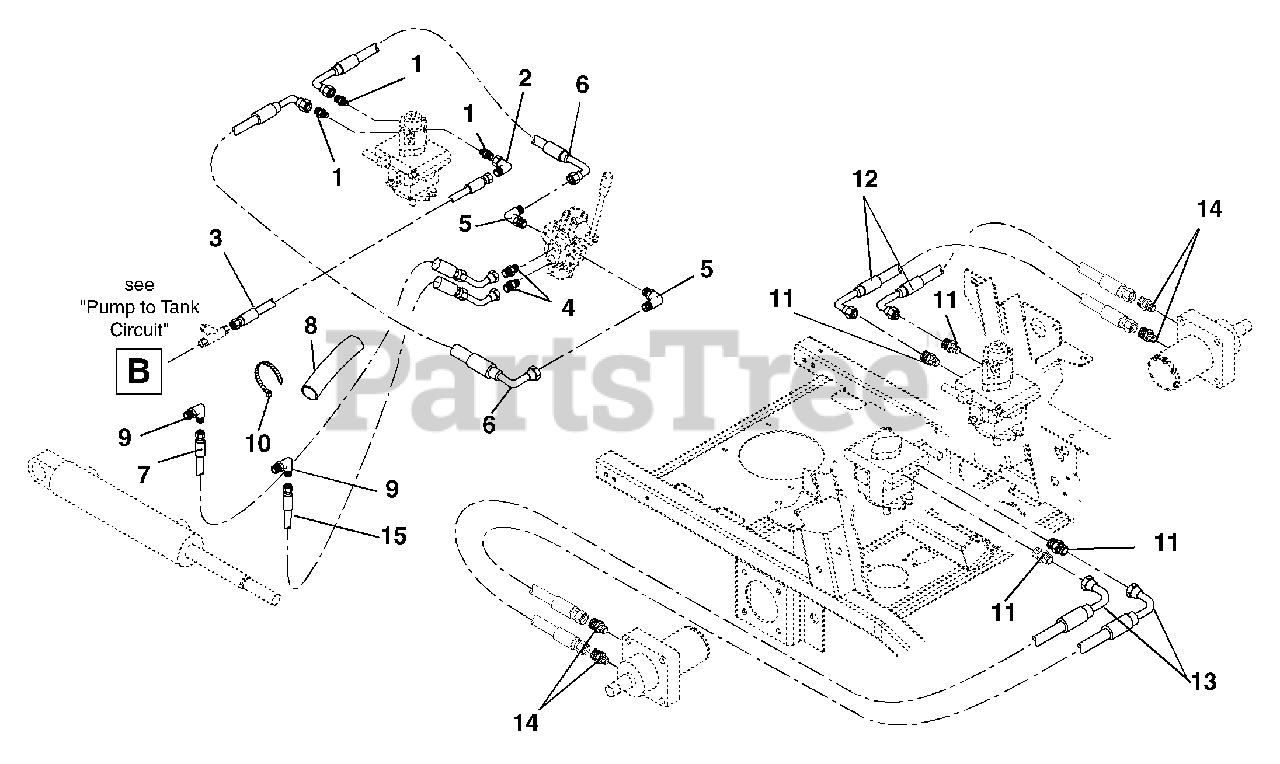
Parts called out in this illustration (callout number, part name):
2	Adapter
3	Hose-Hydraulic
4	Fitting, Hydraulic
5	Fitting, Hydraulic Elbow
6	Hose Hydraulic
7	Hose-Hydraulic
8	Sleeve Protective 24"
9	Fitting, Hydraulic Elbow
10	Cable Tie
11	Adapter-Hydraulic
12	Hose-Hydraulic
13	Hose-Hydraulic
14	Adapter-Hydraulic
15	Hose-Hydraulic
